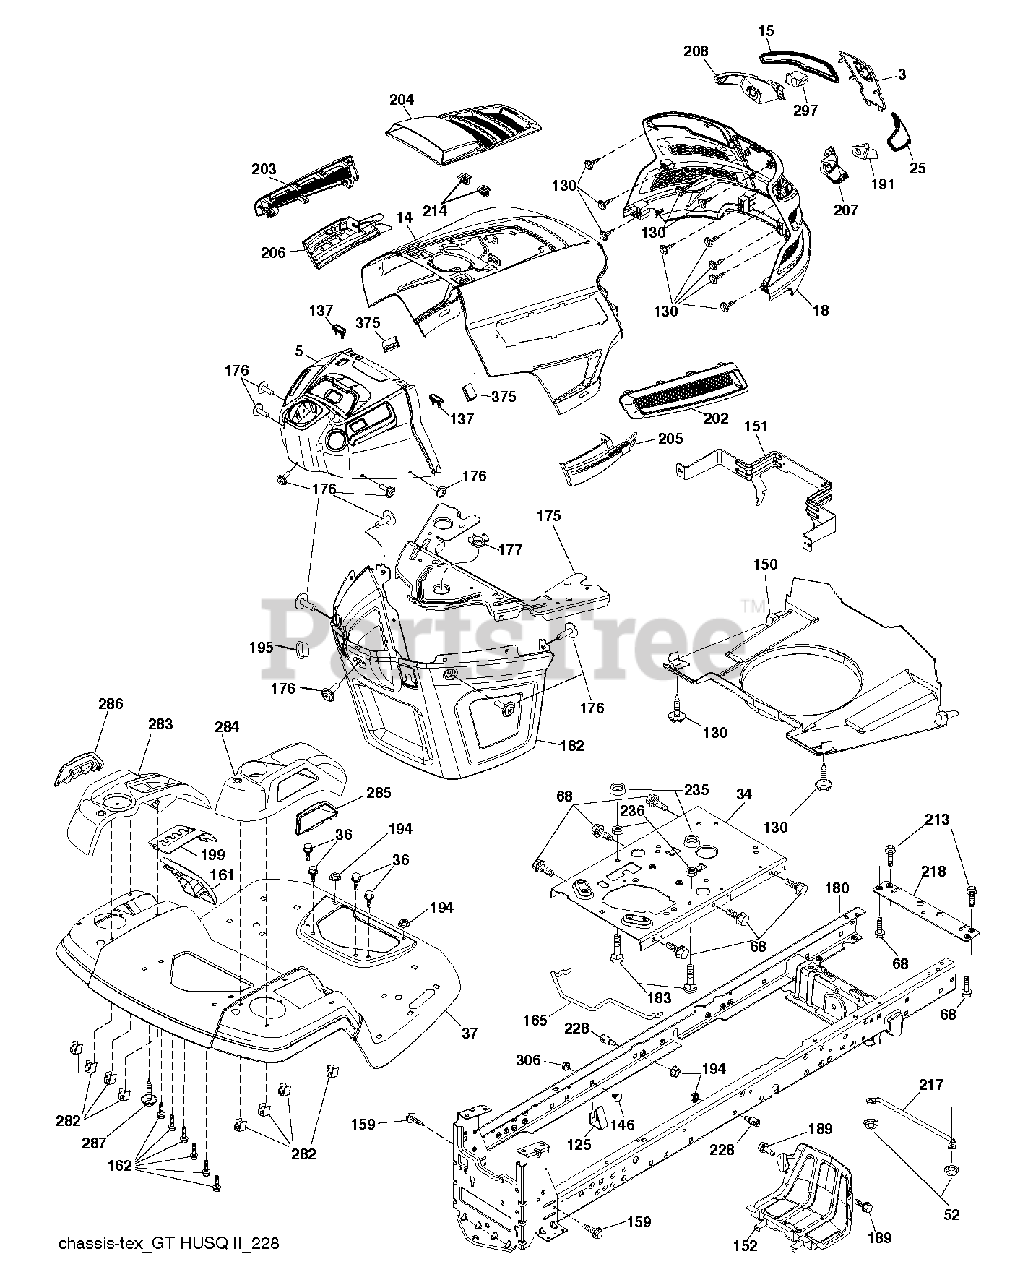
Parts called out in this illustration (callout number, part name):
3	APPLIQUE.SUBASM.GT.HUSQ.II
5	UPPER.GT2.SVC.MINDING.C-O.M;H
14	HOOD.ASM.HUSQVARNA.GT.TEX.ORAN
15	LENS.HEADLIGHT.LH.GTII.2011
18	GRILLE.SUBSTRATE.2011.
25	LENS.HEADLIGHT.RH.GTII.2011
34	PLATE.ENGINE.WELDED.CHASSIS
36	SCREW 5/16"
37	FENDER.TLT.FS.W/CPH/FW/RSF.668
52	LOCKNUT
68	SCR 5/16-18 X 1/2 SELFTAP ZN
125	CLIP.FUEL.LINE
130	SCREW.#10 X 0.750.BOS
137	BUMPER DASH
146	BOLT.RDHD.SHT.SQNK.3/8-16X5/8
150	AIR DUCT.GTV2(1.66"RING HEIGHT
151	BRACKET.PIVOT.HOOD.GT.HUSQ.II
152	SHIELD.BROWNING.PNT.GT.V2
159	SCREW, 3/8-16X3/4
161	WINDOW.FUEL.LT.HUSQ.TEX.498
162	SCREW.HI-LO.CONSOLE
165	SUPPORT.TANK.REAR.W/TEX
175	Crossmember Plate
176	SCREW.#10-24X5/8.RN.QU
177	BUSHING STEERING
180	CHASSIS
182	DASH LOWER.HUSQ.PRED NO CRUISE
183	BOLT.5/16-18X1-1/4 FULL THD
189	SCREW
191	INSERT.REFLECTIVE.RH.HUSQ.GTII
194	NUT LOCK HEX FLANGE 5/16-18
195	PLUG.HOLE.DASH.LOWER.12V.BLK
199	PLATE.DECK.LIFT.HUSQ.LT
202	VENT.SIDE.RH.GT.HUSQ.II.
203	VENT.SIDE.LH.GT.HUSQ.II.498
204	VENT.TOP.HUSQ.GT2
205	SIDE.TRIM.RH.GT.HUSQ.II
206	SIDE.TRIM.LH.GT.HUSQ.II.GRAY
207	BEZEL LIGHT.RH.GT.II.MYLAR
208	BEZEL LIGHT.LH.GT.II.MYLAR
213	HCS 5/16C X 3/4
214	CLIP.RETAINER.TINNER.
217	ROD.PIVOT.HOOD
218	X-PIECE.HOOD.STOP.NON/
228	STUD.FASTNER.W/ANTI-ROTATE
235	SPACER FENDER
236	NUT.CENTERLOCK.5/16-
282	CLIP.RETAINER.CONSOLE.LT.HUSQ
283	CONSOLE.ASM.LFT.RSF.HUSQ.LT
284	CONCOLE.CNTRL.PDL.HUSQ.LT.498
285	CONSOLE INSERT RH
286	CONSOLE.INSRT.LH.HUSQ.LT.BLACK
287	SCREW 1/4X20
297	INSERT.REFLECTIVE.LH.HUSQ.GTII
306	NUT LOCK FLG 3/8-16 UNC
375	BUMPER CLIP-ON. DASH 1"
